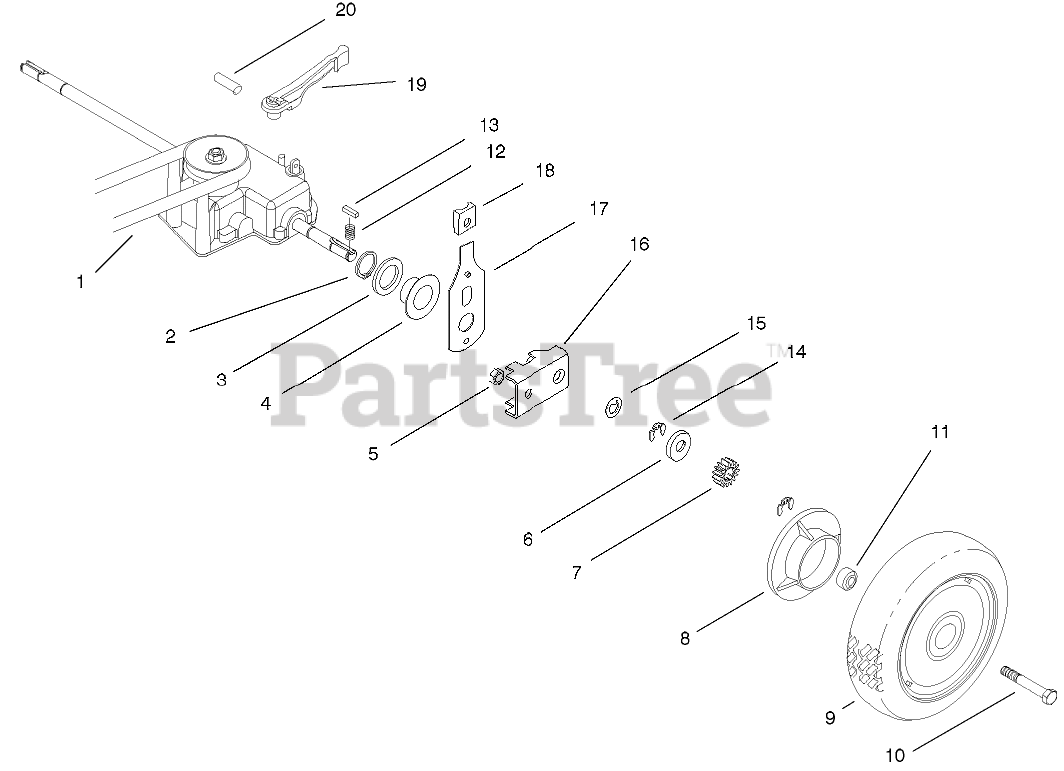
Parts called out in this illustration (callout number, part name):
1	V-BELT
2	RING-RETAINING
3	WASHER
4	CAP-END
5	NUT-LOCK, CONE
6	WASHER-THRUST, OUTER
7	GEAR-PINION
8	COVER-WHEEL
9	WHEEL AND TIRE ASM
10	SCREW-HH
11	SPACER-COVER, WHEEL
12	SPRING-COMPRESSION
14	RING-RETAINING
15	WASHER-THRUST, OUTER
16	PIVOT ARM ASM
17	REAR SPRING ARM ASM
18	KNOB-ARM
19	LEVER-SHIFT
20	PIN-COIL
